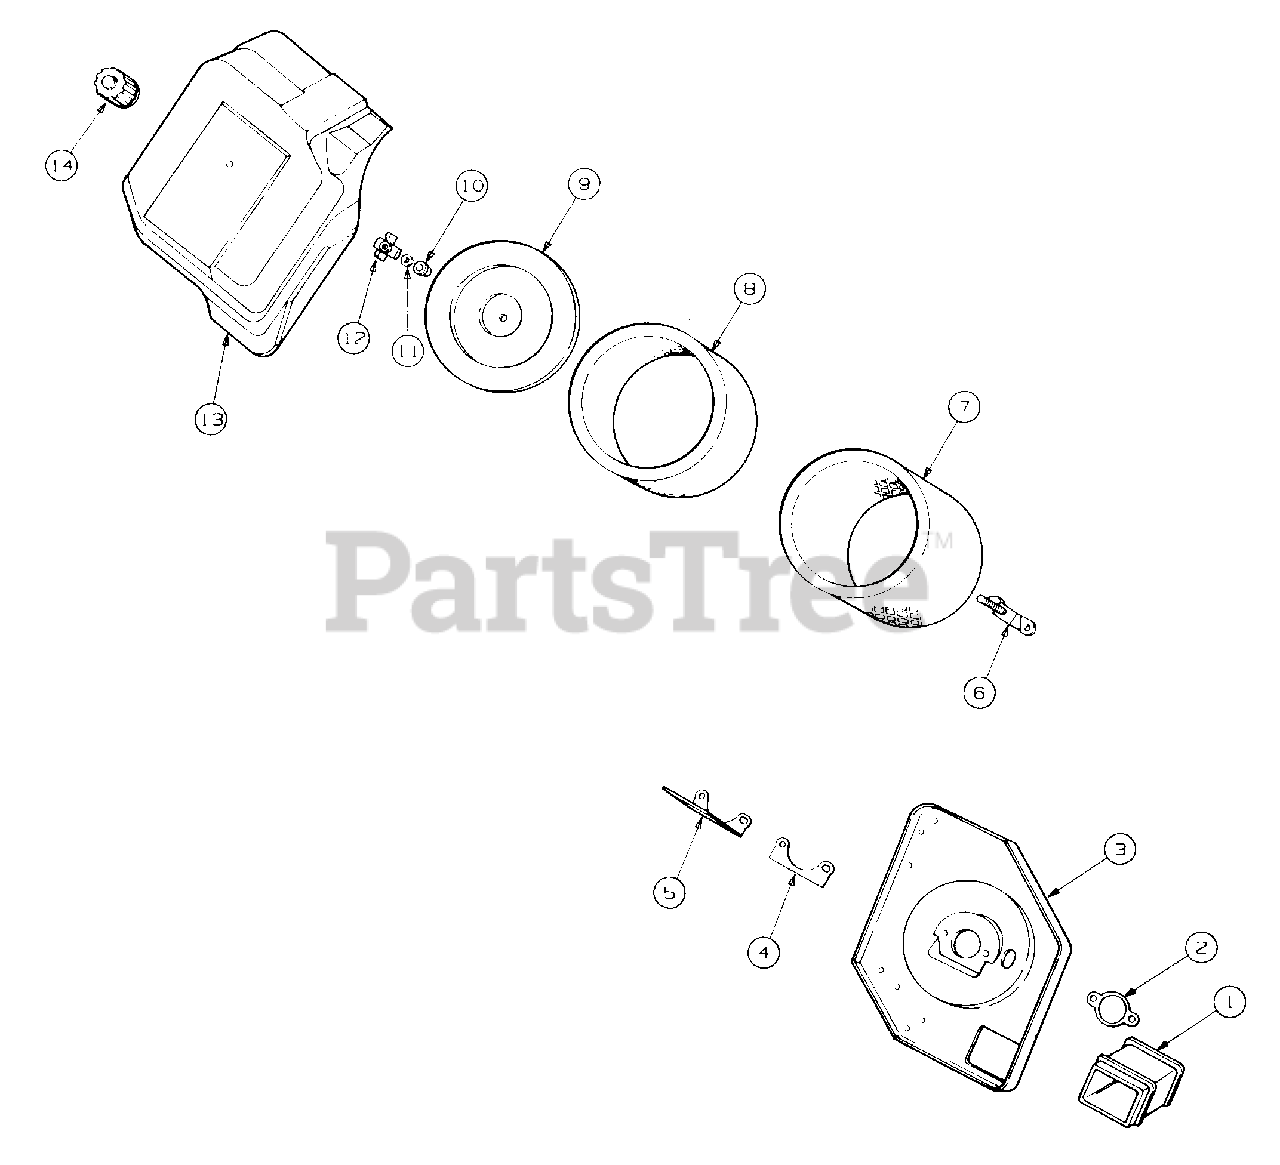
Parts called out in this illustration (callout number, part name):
1	Tube, Air Intake
2	Gasket, Air Cleaner
3	Base, Air Cleaner
4	Gasket, Collector Plate
5	Plate, Air Cleaner
6	Bracket, Air Cleaner
7	Element, Air Cleaner
8	Precleaner, Element
9	Cover, Element
11	Washer, Plain, 1/4
13	Cover, Air Cleaner
14	Knob, Air Cleaner Cover
